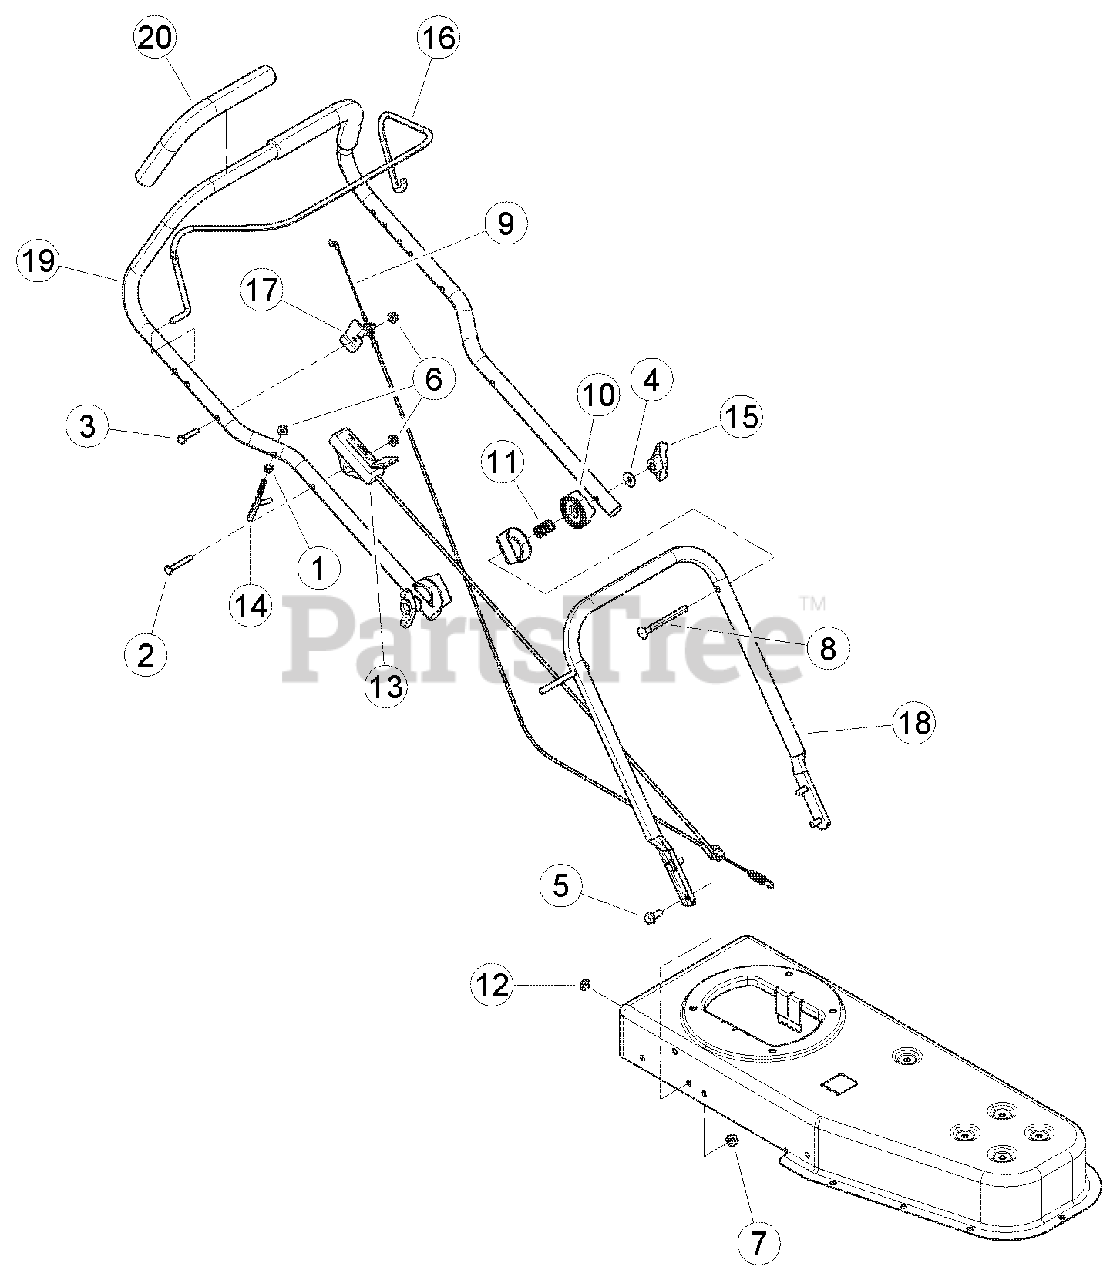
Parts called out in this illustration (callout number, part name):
1	NUT, 1/4 SERR FLANGE
2	BOLT, 1/4 X 1-3/4 HEX
3	BOLT, 1/4 X 1-1/4 HEX GR5 ZP
4	WASHER, 5/16 FLAT
5	BOLT, 5/16 X 3/4 SERR FLANGE UNC
6	NUT, 1/4-20 NYLOCK FLANGE
7	NUT, 5/16-18 NYLOCK FLANGE
8	BOLT, 5/16-18 X 3-1/2 CRG LONG NECK GR5 ZP
9	CABLE, TRIMMER ENGAGEMENT
10	RETAINER,HANDLEBAR ADJUSTMENT
11	SPRING, RETAINER COMPRESSION
12	GROMMET, 3/8 ID X 5/8 OD
13	CONTROL, THROTTLE
14	GUIDE, RECOIL
15	KNOB, 5/16-18 UNC TEE
16	BAIL, CONTROL
17	BRACKET, CABLE ANCHOR
18	SUPPORT, TRIMMER HANDLE
19	ASSEMBLY, TRIMMER HANDLE BAR, SERVICE PART
20	PAD, FOAM HANDLEBAR (32022-00)
